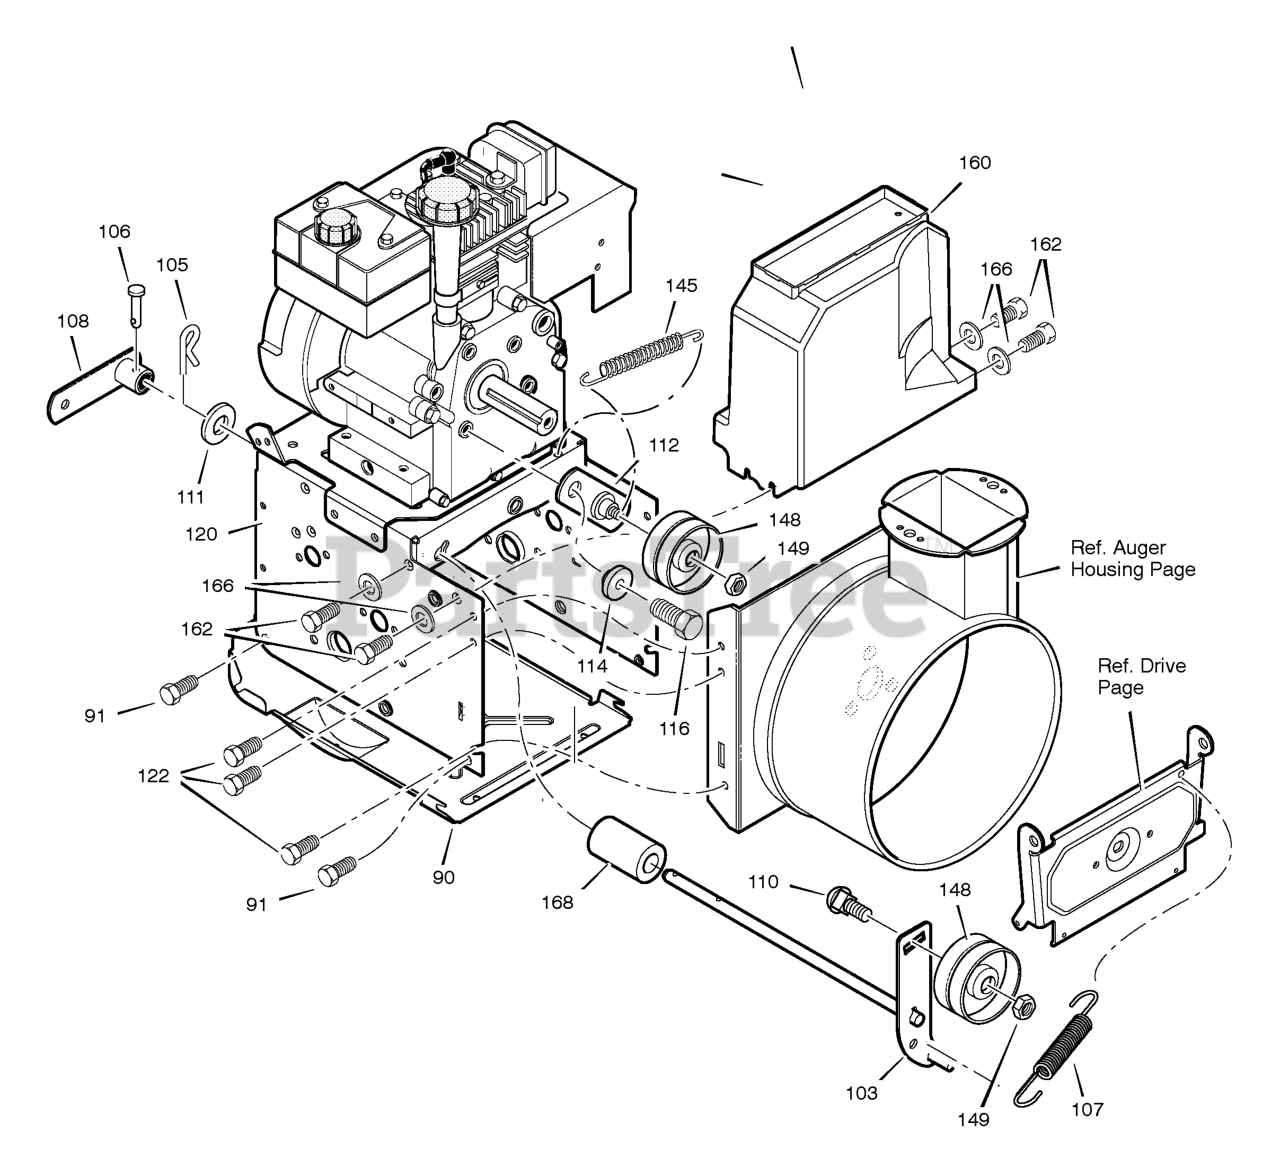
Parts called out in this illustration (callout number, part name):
90	COVER, BOTTOM
91	SCREW, 1/4-20X .63
103	IDLER ASSEMBLY, AUGER
105	PIN, HAIR .38DIAX1.64LG
106	PIN, KLIK 3/16" DIA
107	SPRING, TENSION
108	ASSY., SPRING ATTACH
110	BOLT, 3/8-16X1.25 CARR.
111	WASHER, FLAT
112	BRACKET ASSEMBLY, IDLER
114	BUSHING, IDLER BRACKET
116	SCREW 5/16-24 X .75
118	WASHER, SPLIT
122	SCREW, TAP 5/16-18 X .50
145	SPRING, IDLER TRACTION DRIVE
148	PULLEY, IDLER
149	NUT, JAM 3/8-16
160	COVER, BELT
162	SCREW, TAP 1/4-20 X .63
166	WASHER, FLAT
168	SPACER, AUGER BRACKET
